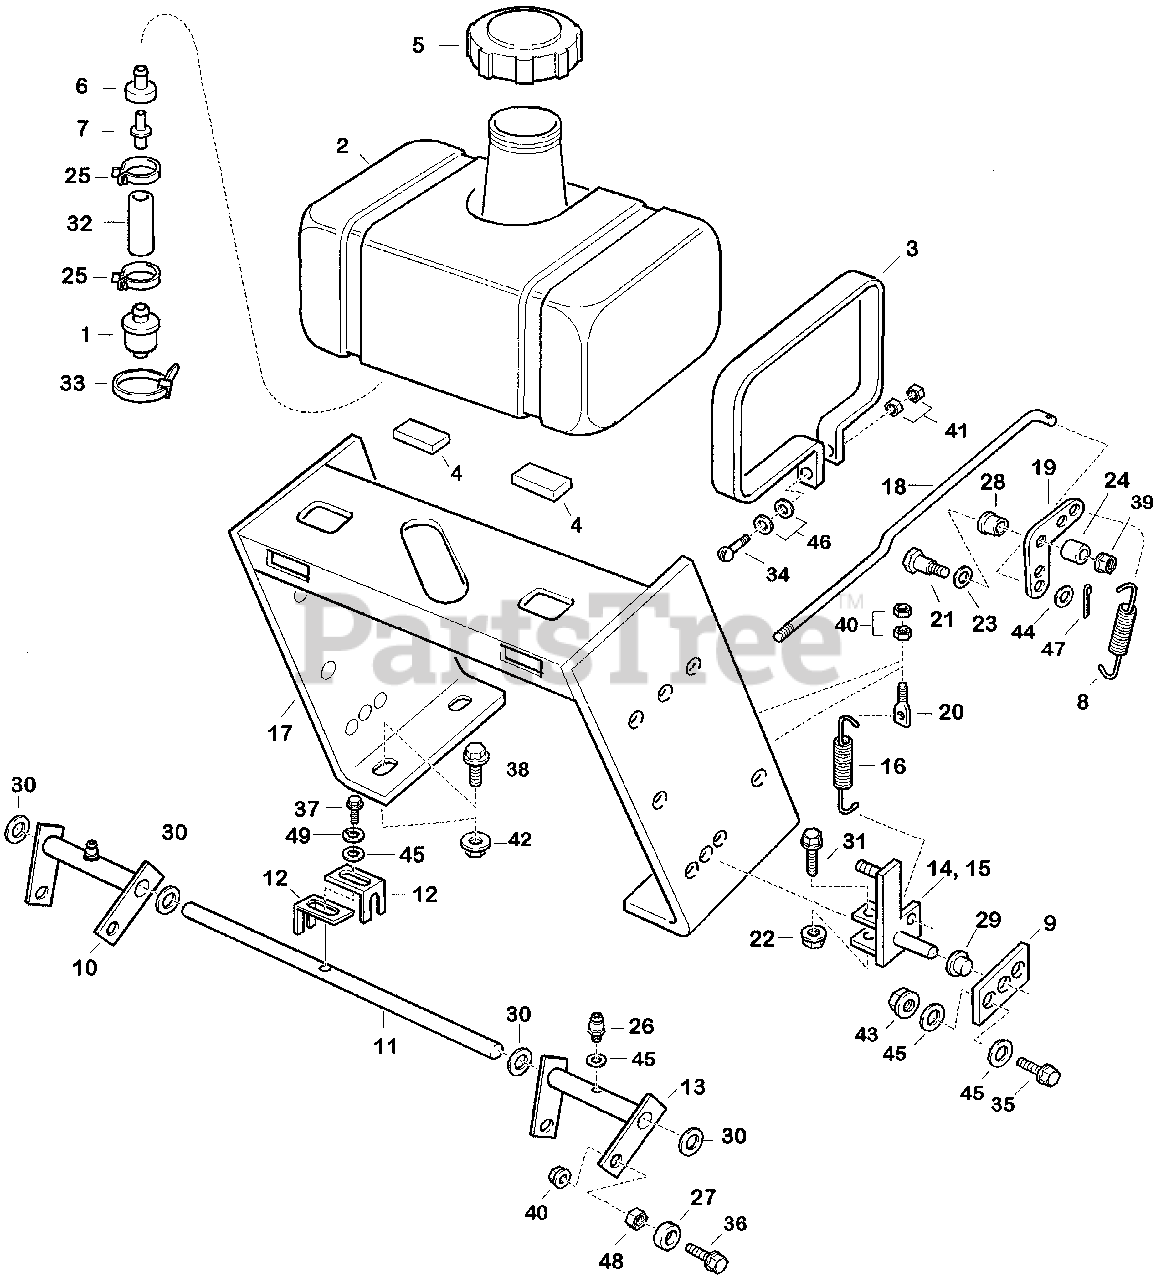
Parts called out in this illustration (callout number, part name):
1	FILTER, FUEL
2	TANK, FUEL (4.2)
3	STRAP, FUEL TANK
4	PAD, FUEL TANK
5	CAP, FUEL TANK
6	JOINT, CONNECTOR FUEL
7	PIPE, FUEL
8	SPRING, TENSIONER
9	SUPPORT, PUMP SHAFT
10	ARM, R. SPEED STOP
11	SHAFT, CROSS
12	SPACER, CROSS SHAFT
13	ARM, L. SPEED STOP
14	ARM, R. PUMP
15	ARM, L. PUMP
16	SPRING, PUMP ARM
17	SUPPORT, HANDLE
18	ROD B, P.T.O.
19	BELLCRANK (3")
20	BOLT, SPRING ADJUSTER
21	BOLT, SHOULDER (3/8"-16)
22	NUT, SELF-LOCK (5MM)
23	WASHER, BELLEVILLE (1/2")
24	SPACER (1/2")
25	CLAMP, FUEL LINE
26	NIPPLE, GREASE
27	BEARING, PUMP STOP
28	BUSHING, SNAP
29	BUSHING, PUMP ARM
30	BUSHING (5/8")
31	BOLT, HEX. (5X25)
32	LINE, FUEL (24")
